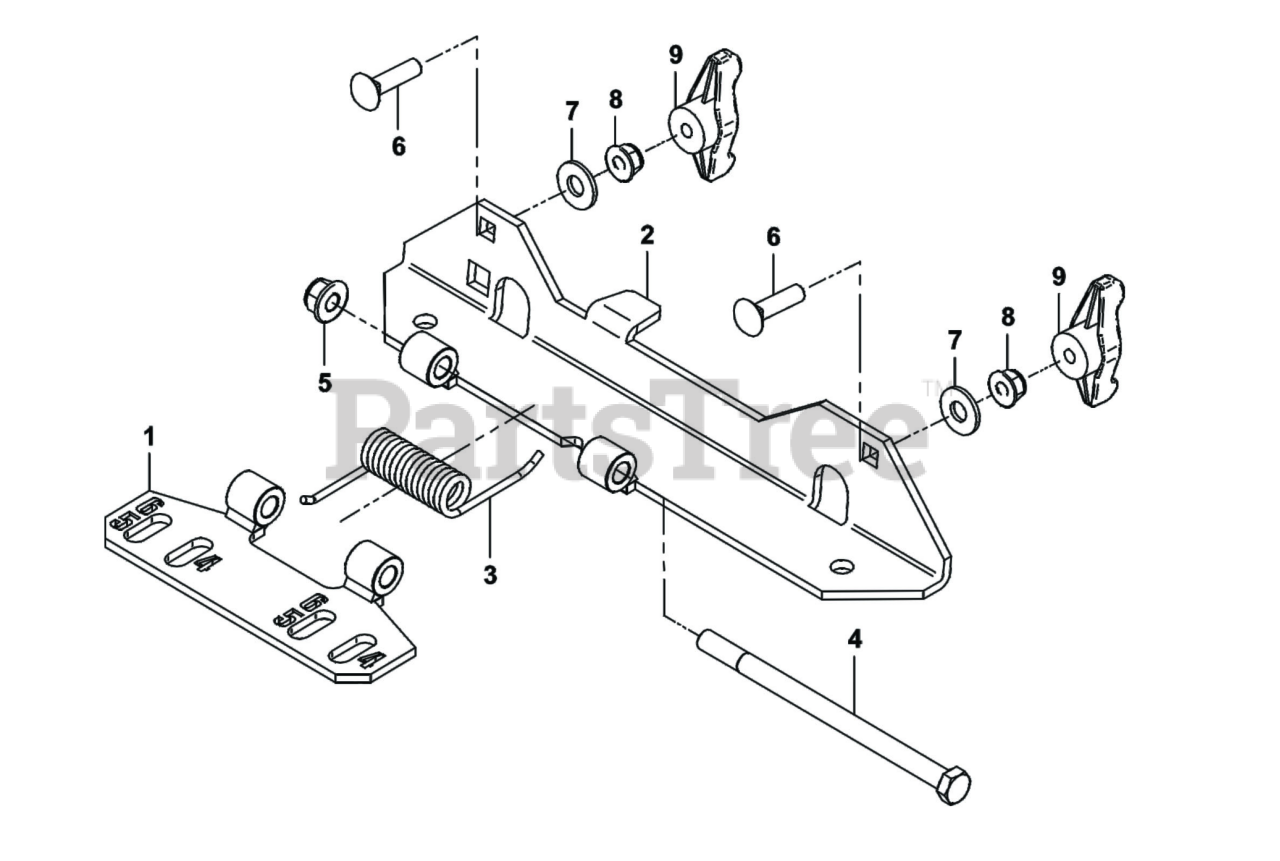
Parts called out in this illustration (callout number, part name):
1	BOOT PLATE ASSEMBLY
2	DECK PLATE ASSEMBLY
3	TORSION SPRING
4	SCREW 3/8"-16 x 6" (GR5)
5	LOCKNUT-NYLON FLAN
6	CARRIAGE BOLT 5/16"-18 X 1.25"
7	FLAT WASHER
8	NUT-FLANGE LOCK 5/
9	WING KNOB (5/16"-18)
